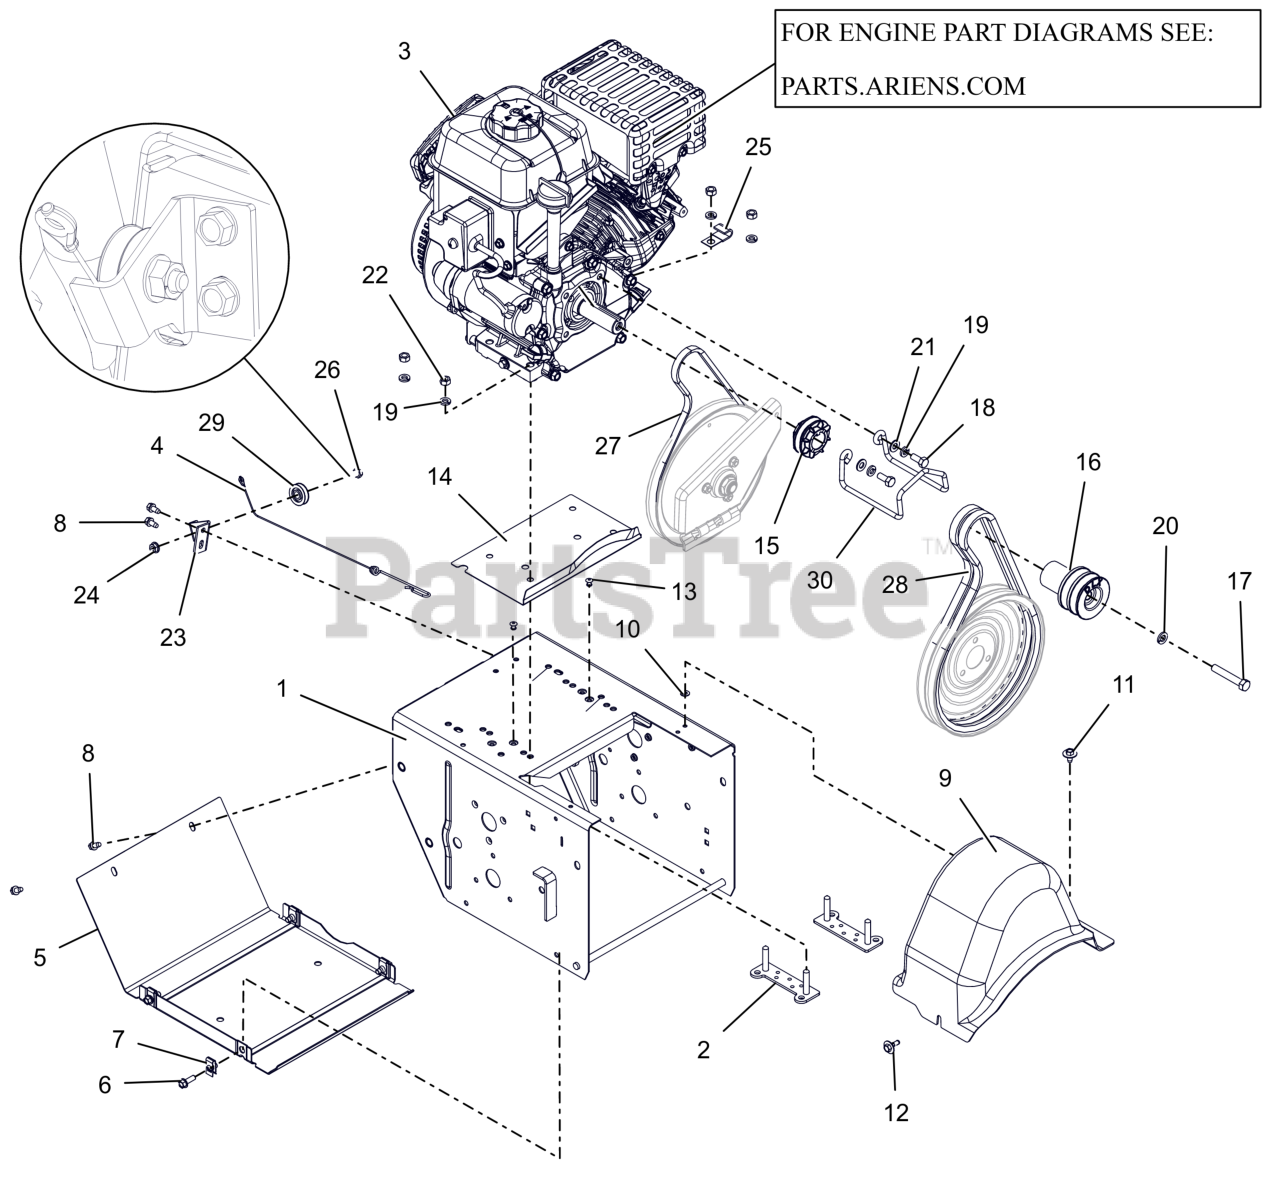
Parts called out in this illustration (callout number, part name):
1	FRAME, MAIN - 14GA DELUXE (ORANGE)
2	STRAP, BOLT - SMALL ENGINE
3	ENGINE, AX254 GEN2 120V/60W
4	CABLE, LOWER TRACTION,SS & PRO
5	COVER, BOTTOM
6	BLT, HWH .25-20X.75 G5 ZCC
7	NUT-RTNR .25-20X.56
8	SCR-TAP .25-20X.50 HWH ZCC
9	COVER, BELT-SMALL
10	NUT-PUSH .25X.50 O.D.
11	SCR, TAP .25-20X.50 LG HWH ZCC
12	SCR-TAP .25-20X.5 CAPTIVE
13	RVT, POP .1875 ZCC
14	BAFFLE, WATER-SMALL
15	SHEAVE, DRIVE
16	SHEAVE, ATTACHMENT - STANDARD 2 GRV
17	BLT, HEX .38-24X2.25 G5 ZCC
18	BLT, HEX .31-24X.750 G5 ZCC
19	WSHR, LK-HVY .312X.097 ZCC
20	WSHR,LK-REG .375X.094 ZCC
21	WSHR,FLT .344X.688X.065 ZCC
22	NUT, HEX .312-18 ZCC
23	BRACKET, CABLE PULLEY
24	NUT-LK-TOP-FLG .250-20 GF ZCC
25	J-CLAMP
26	BOLT, SHLDR -.375 X .375 X .25-20
27	V-BELT, 3L-WRAPPED
28	V-BELT, HA-RAW EDGE (SET)
29	PULLEY, CABLE
30	FINGER, BELT
